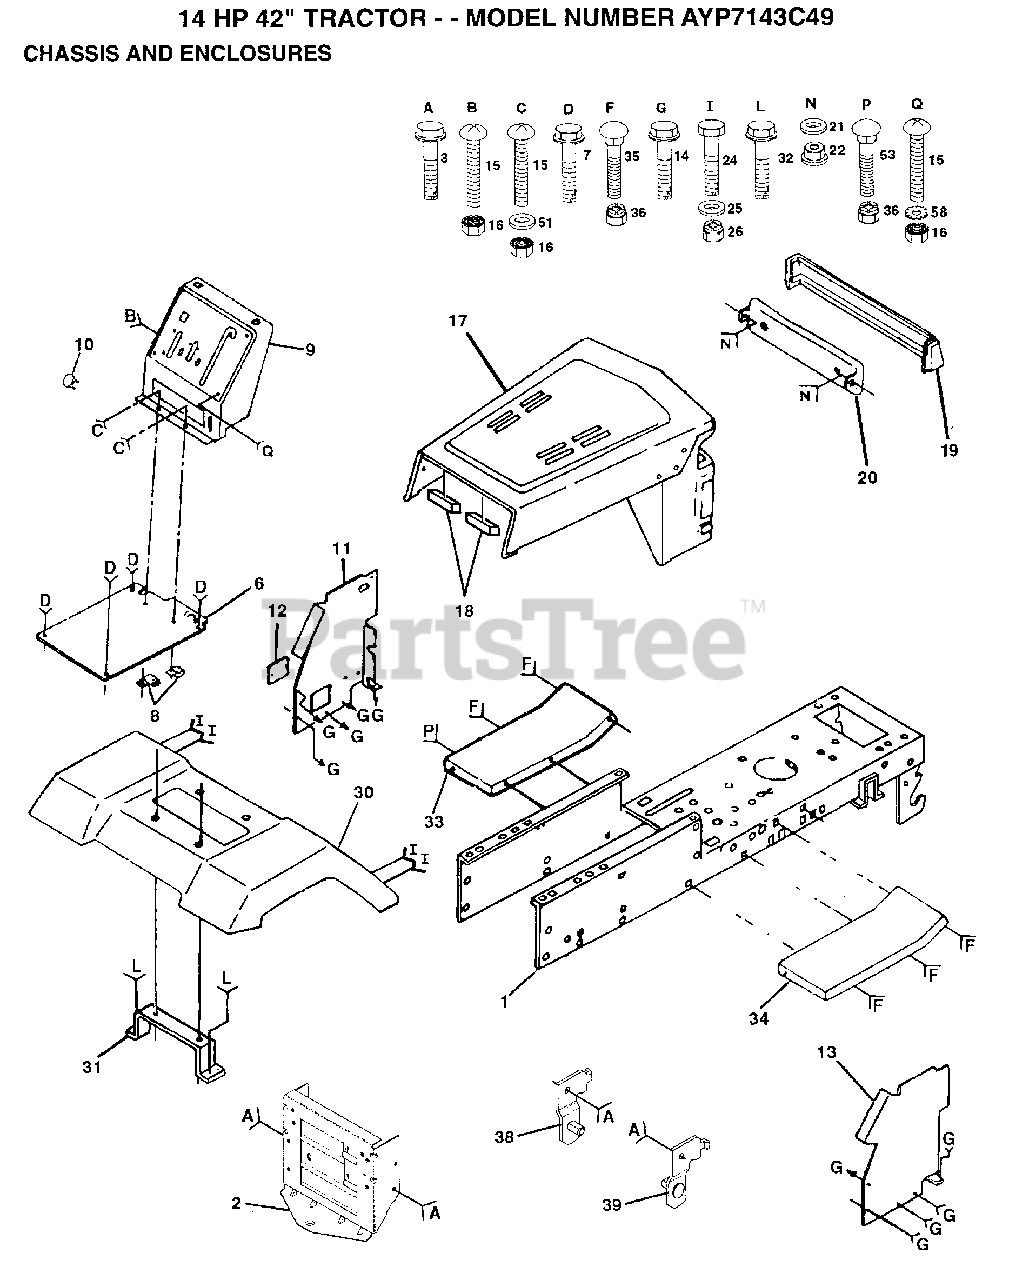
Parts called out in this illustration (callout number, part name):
3	SCREW
7	SCREW
8	CLIP T
9	DASH SILKSCRN 1
10	PLUG BUTTON T
11	PANEL DASH LH
12	COVER ACCESS
14	SCREW LT
15	SCREW
17	HOOD/GRILL ASM
21	WASHER PM
22	PAL NUT LT
24	BOLT
25	WASHER
26	NUT
30	FENDER
31	BRKT FENDER
32	SCREW
33	FOOTREST LH
34	FOOTREST RH
35	BOLT
36	NUT
38	BRACKET ASM LH
39	BRACKET ASM RH
51	WASHER
58	LOCKWASHER
